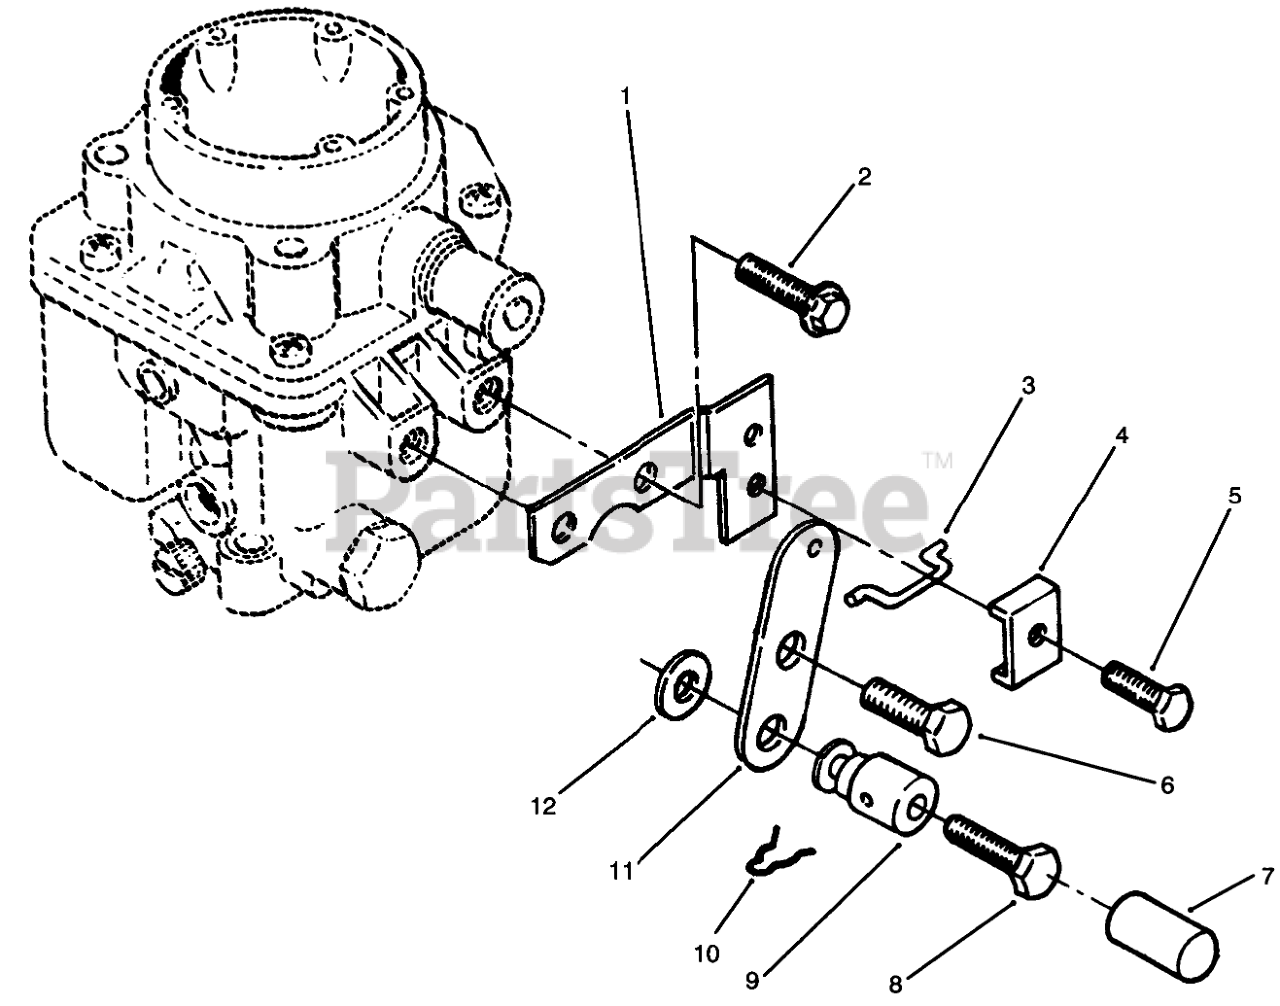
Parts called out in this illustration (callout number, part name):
1	BRACKET
2	SCREW-HWH
3	LINK-CHOKE
5	SCREW-TAPPING
6	MACHINE SCREW
8	SCREW
9	SWIVEL-CHOKE LEVER
10	PIN-COTTER
11	CHOKE-LEVER (PRIMED)
12	Washer
